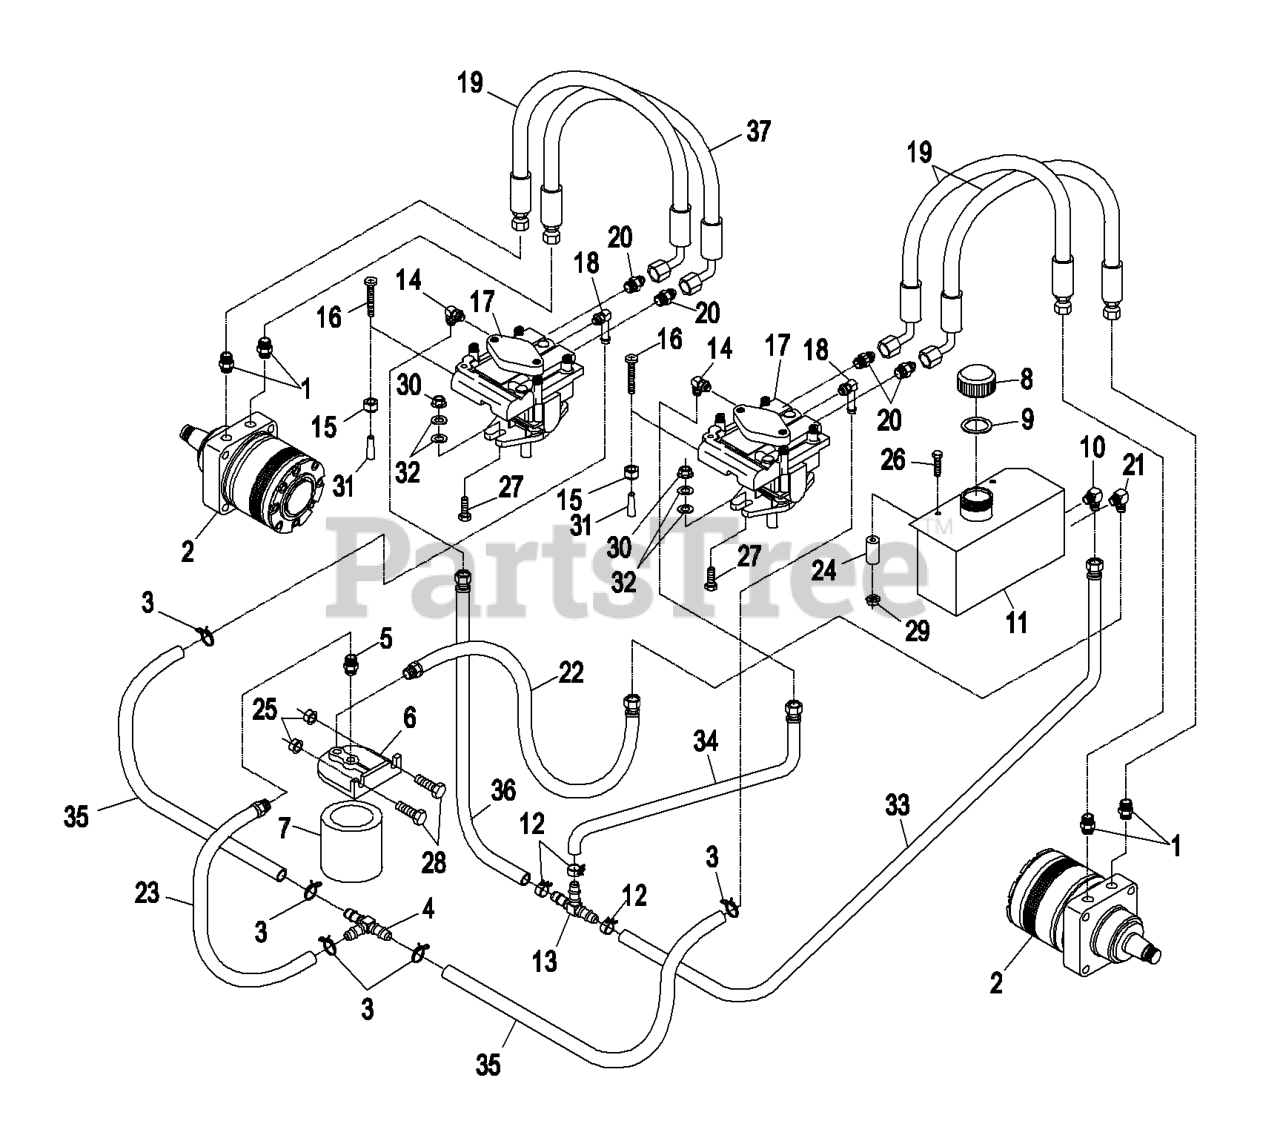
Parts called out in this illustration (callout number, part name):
1	FITTING-STRAIGHT
2	HYD MOTOR ASM
3	CLAMP-HOSE
4	FITTING-TEE, HOSE
5	FITTING-STRAIGHT
9	GASKET-CAP, TANK
10	FITTING-ELBOW
12	CLAMP-HOSE
13	FITTING-TEE, HOSE
14	FITTING-90 DEG
15	NUT-LOCK, NI
18	FITTING
20	FITTING-STRAIGHT
21	FITTING-ELBOW
22	ASM,HOSE LO PRESSURE
23	ASM,HOSE CHARGE LINE
26	SCREW-HH
27	SCREW-HH
28	SCREW-HH
30	NUT-HHF, WHIZ
31	GRIP-VALVE, DUMP
32	WASHER-FLAT
33	ASM,HOSE CASE DRAIN
34	HOSE ASM
36	HOSE ASM
37	HOSE-PRESSURE, HIGH
